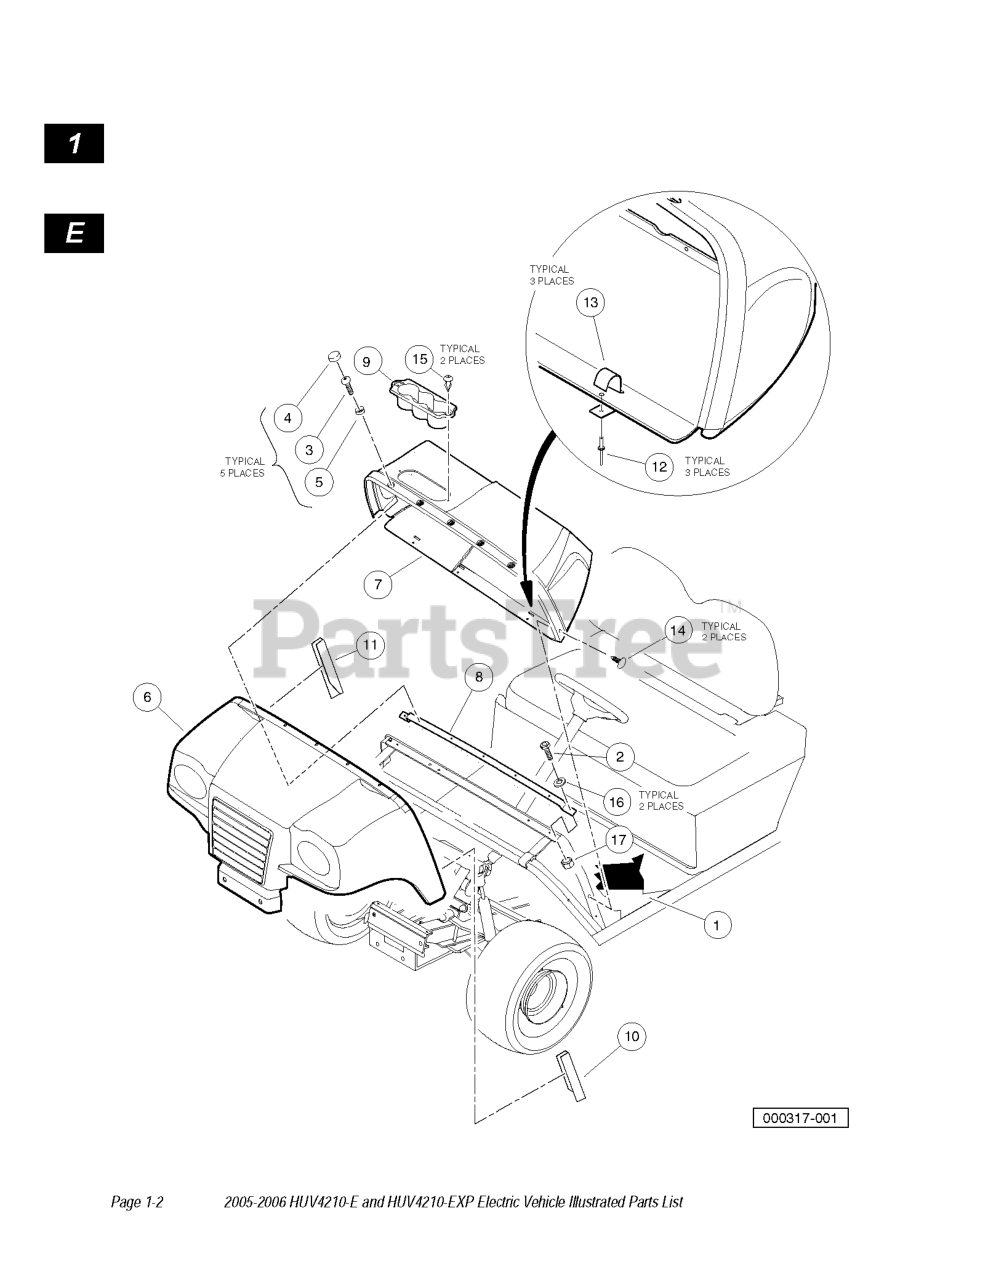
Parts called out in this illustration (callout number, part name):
1	FLOORMAT - DEBADGED
2	SCREW, 1/4-20 X .750 HEX HEAD
3	SCREW 1/4-20X.75 TORX PN HD
4	CAP 1/4" PLASTIC SCREW HEAD
5	WASHER 1/4 ID SCALLOPED PLAST
6	COWL, 4210, ORANGE
7	DASH - H2 FORMED
8	UPPER COWL SUPPORT
9	OBJECT HOLDER
10	COWL COVER, DRIVER
11	COWL COVER, PASSENGER
13	CLIP, DASH
14	PUSH PIN, BLACK
15	SCREW, TUFLOK PANEL, 1/4
16	WASHER 1/4 FLAT
17	LOCKNUT, 1/4-20 NYLON INSERT
